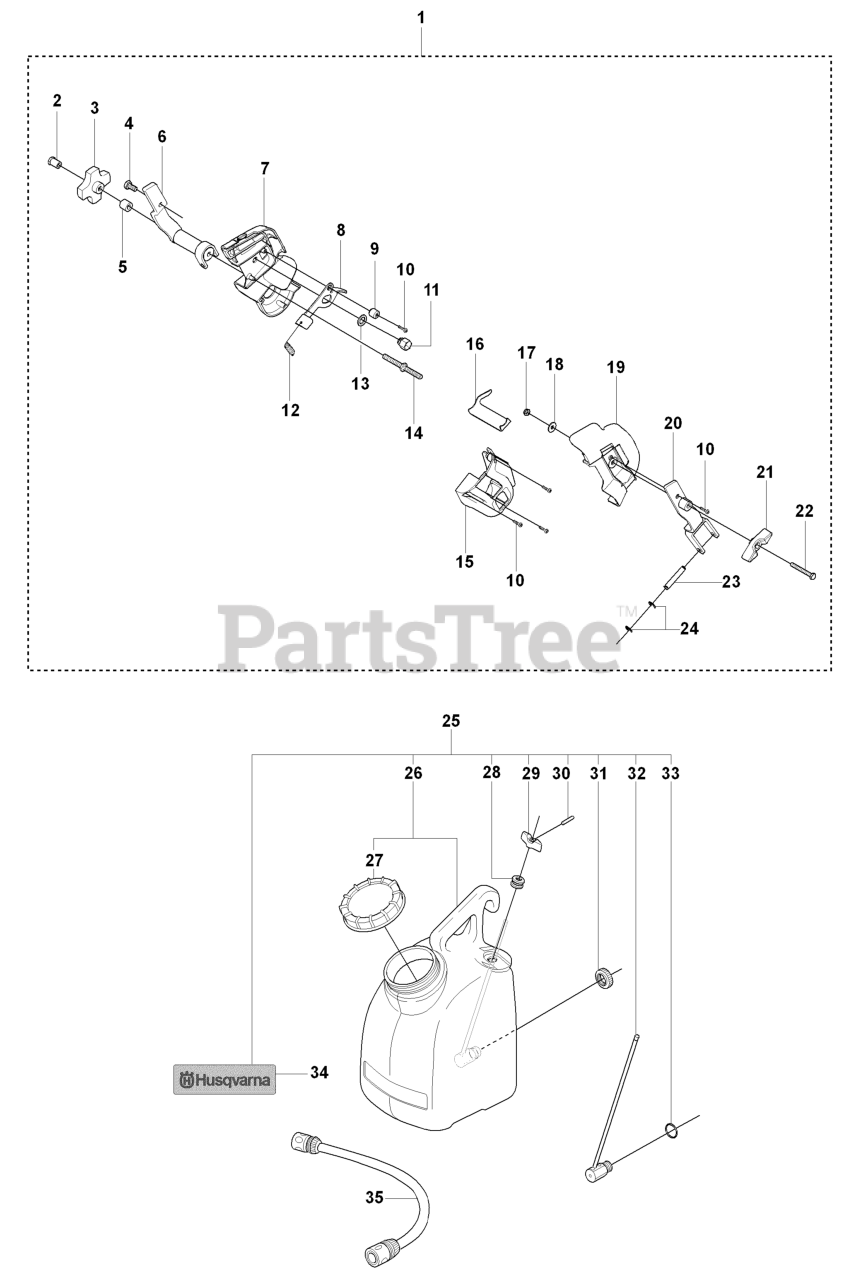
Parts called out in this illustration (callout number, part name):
1	HOLDER ASSY
3	KNOB
4	REPL BY 725 24 49-51
5	SPACING SLEEVE
17	NUT FLANGE - M6
18	WASHER
22	SCREW M6X50
25	WATER TANK
26	TANK
28	ANTIVIBE ELEMENT
35	HOSE
